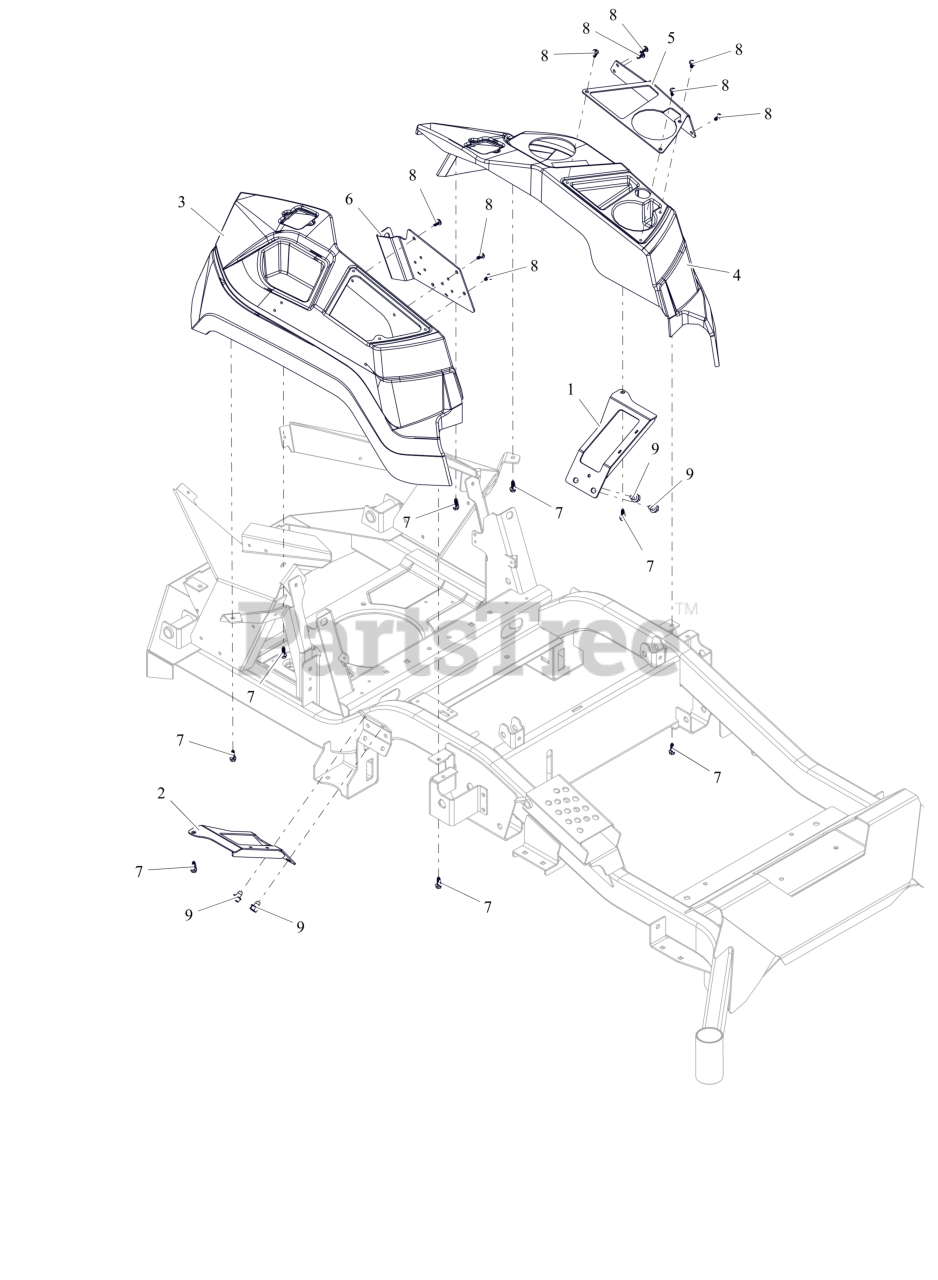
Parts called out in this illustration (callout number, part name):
1	WLDMT, LH FENDER MOUNT
2	WLDMT, RH FENDER MOUNT
3	FENDER, RH APEX - 2017
4	FENDER, LH APEX
5	PLATE, APEX CUP HOLDER COVER
6	BRKT, FENDER/RELAY MOUNTING
7	SCR, PLASTITE .25-10X.75 ZCC
8	SCR-PAN .25-15X.50 6L H/LZB500
9	SCR,TAP .375-16X.50 HWH TR ZCC
